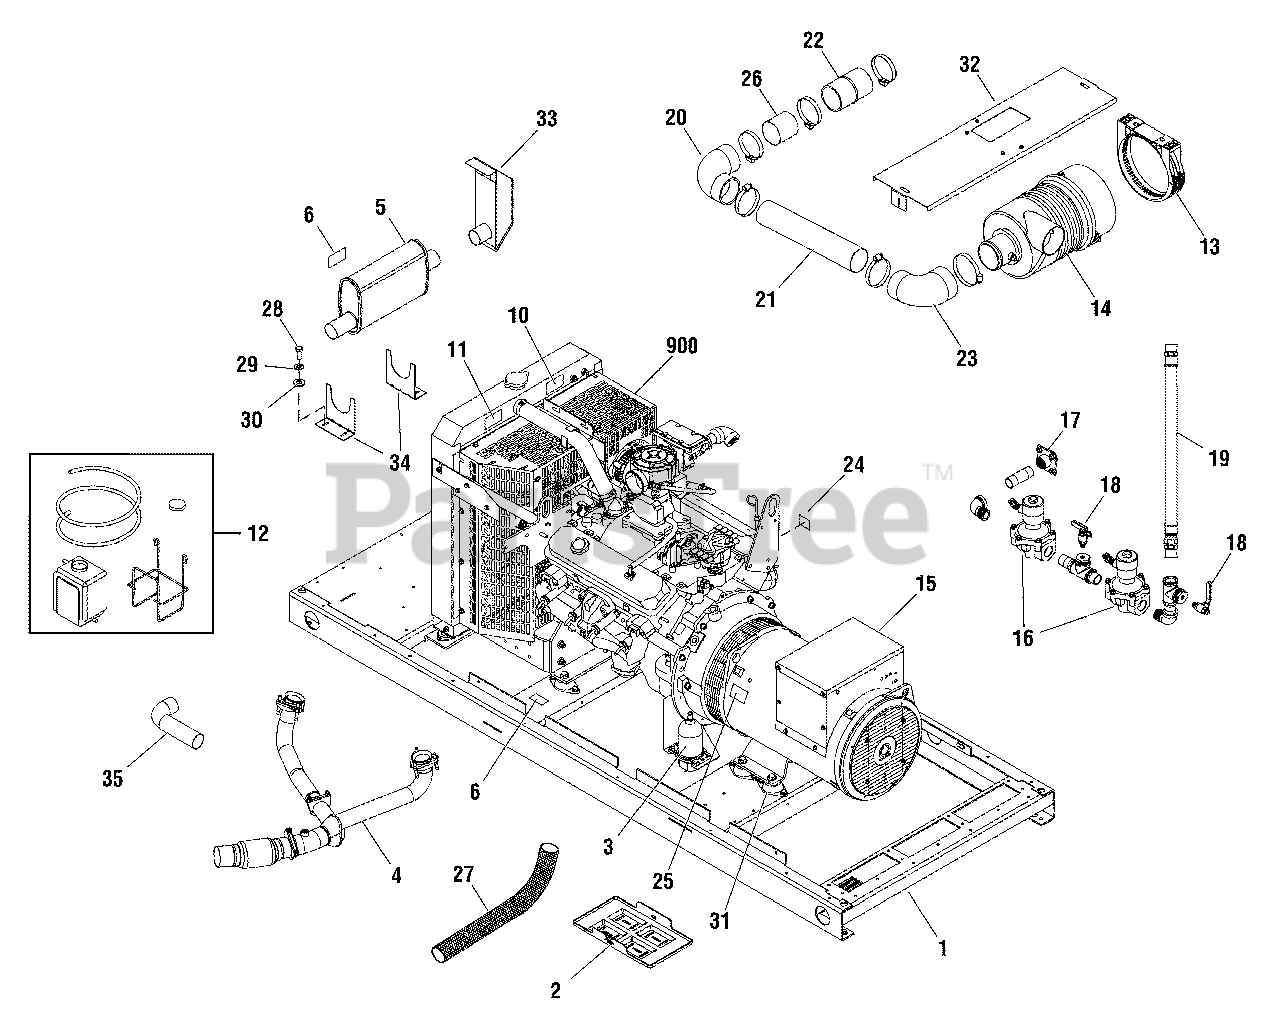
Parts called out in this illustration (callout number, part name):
4	KIT, Exhaust
5	MUFFLER
6	DECAL
11	DECAL
12	BOTTLE, Overflow
16	VALVE, Fuel
24	DECAL
28	* CAPSCREW, Hex, Head, 1/4-20 x 3/4
29	* WASHER, Lock, 1/4-M6
30	* WASHER, 1/4
31	MOUNT, Vibration
33	DIFFUSER
34	BRACKET, Muffler
900	** ENGINE
